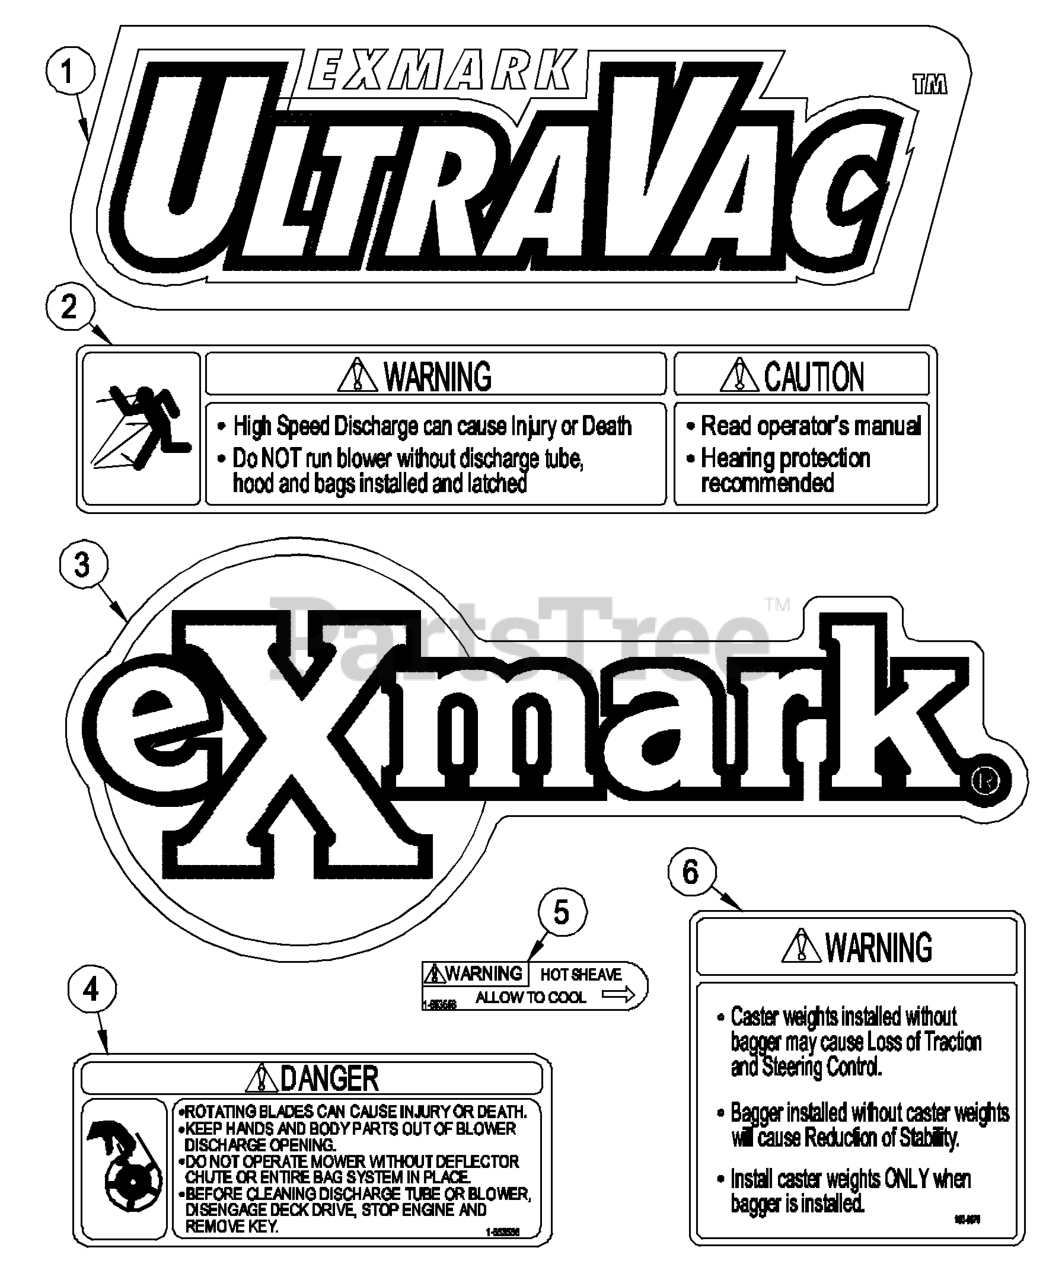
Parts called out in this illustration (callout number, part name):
1	DECAL, ULTRAVAC
2	DECAL,DISCHARGE WARNING
3	DECAL, EXMARK LOGO
4	DECAL, IMPELLER WARNING
5	DECAL-WARNING
